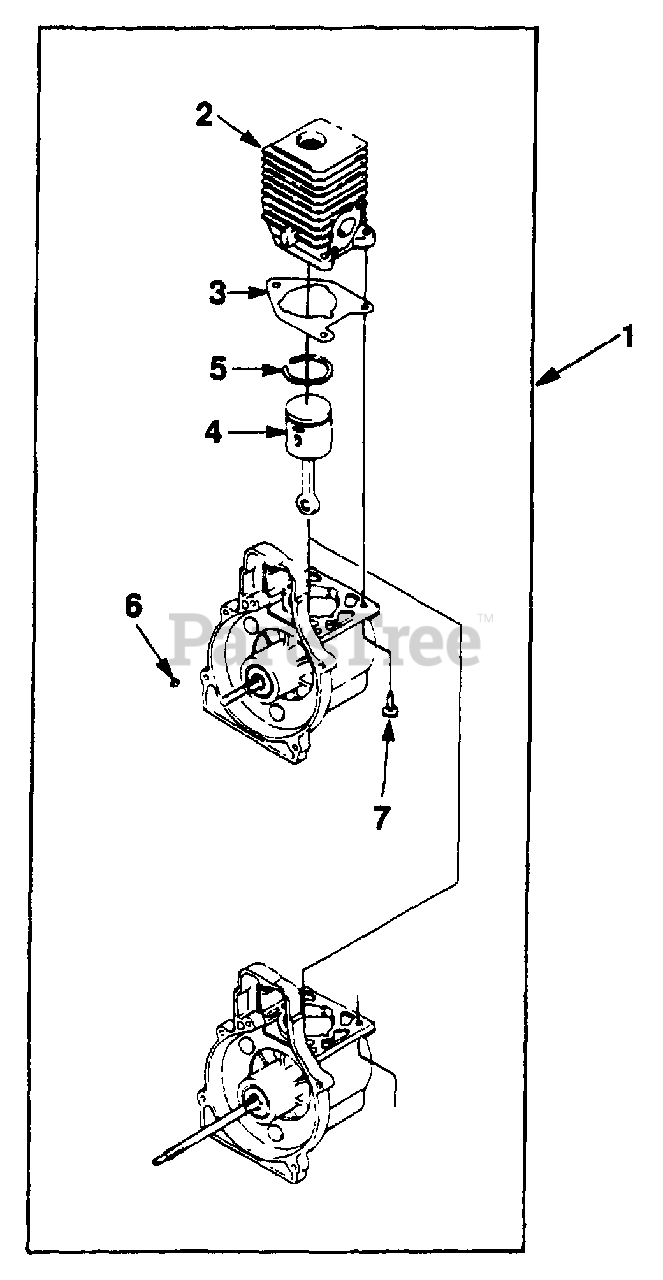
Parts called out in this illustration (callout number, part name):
1	SHORT BLOCK
2	CYLINDER & GASKET
3	GASKET-Cylinder
4	PISTON & ROD
5	RING-Piston
6	KEY-Woodruff
7	SCREW-Torx Pan Hd (10-24 X 3/4")
